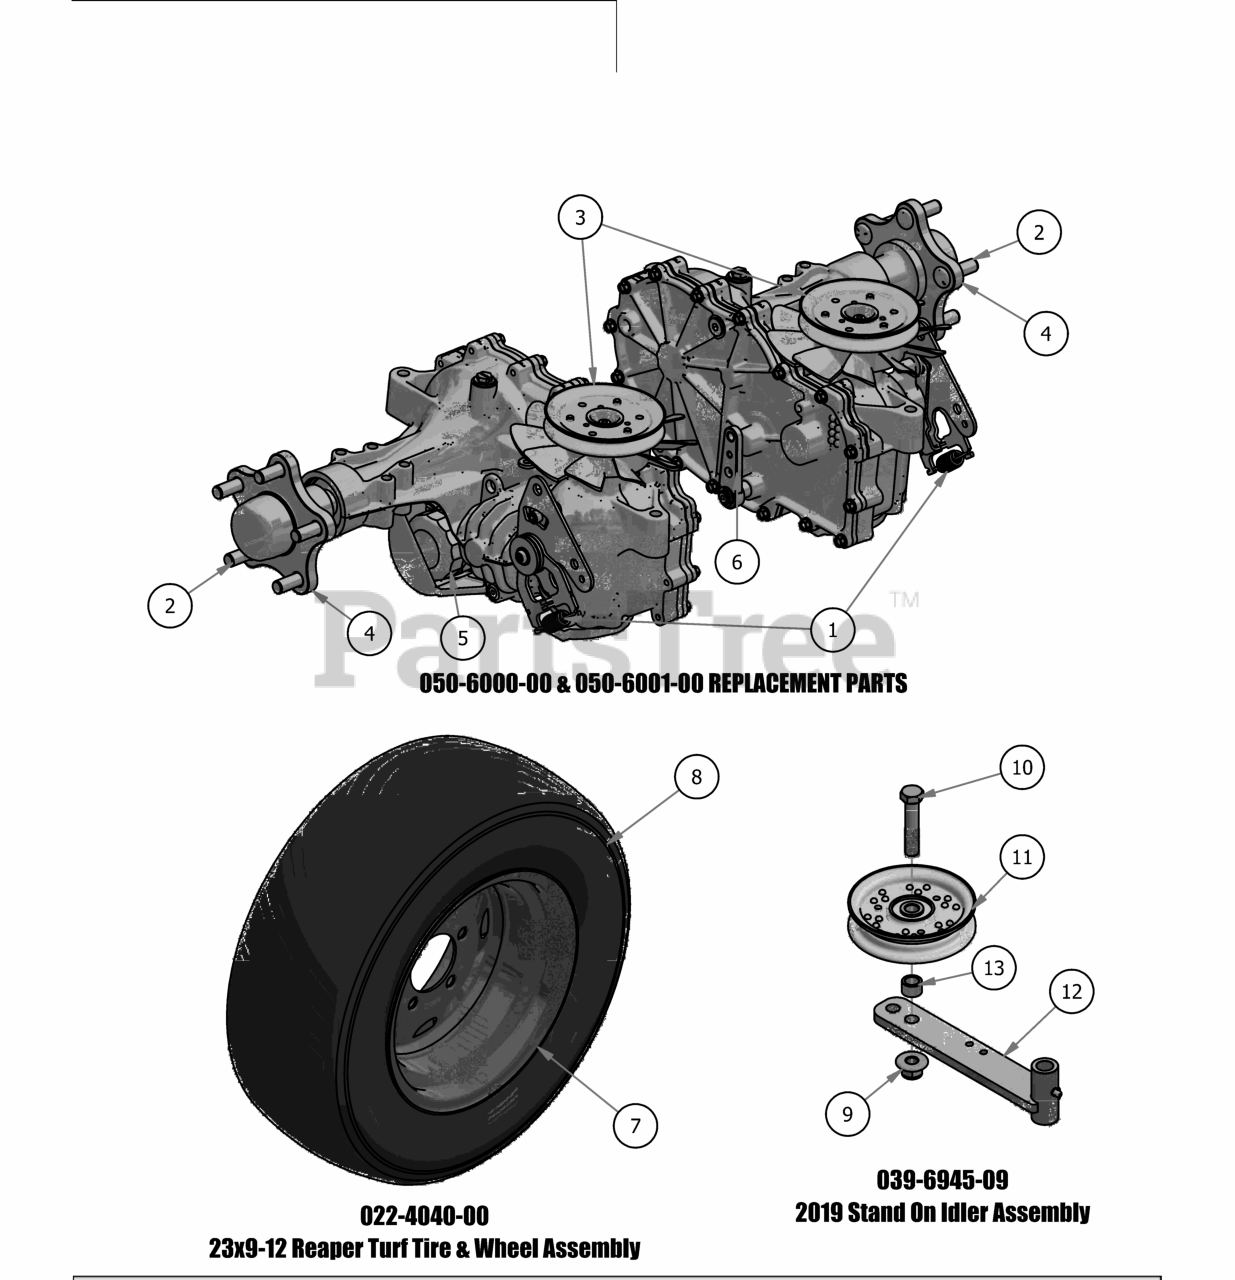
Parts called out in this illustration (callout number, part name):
1	Transaxle Spring
2	Transaxle Wheel Studs
3	Fan/Pulley Kit
4	5 Bolt Hub Kit
5	Transaxle filter
6	Transaxle Brake Lever
7	12x7" Black Wheel
8	23x9-12 Reaper Turf Tire Only
9	1/2-13 Nylon Flange Nut
10	1/2" x 2 1/2" Hex Bolt
11	4 3/4 Idler Pulley - ABFI-76
12	Deck Idler
13	1/2 x 1/2 Spacer
